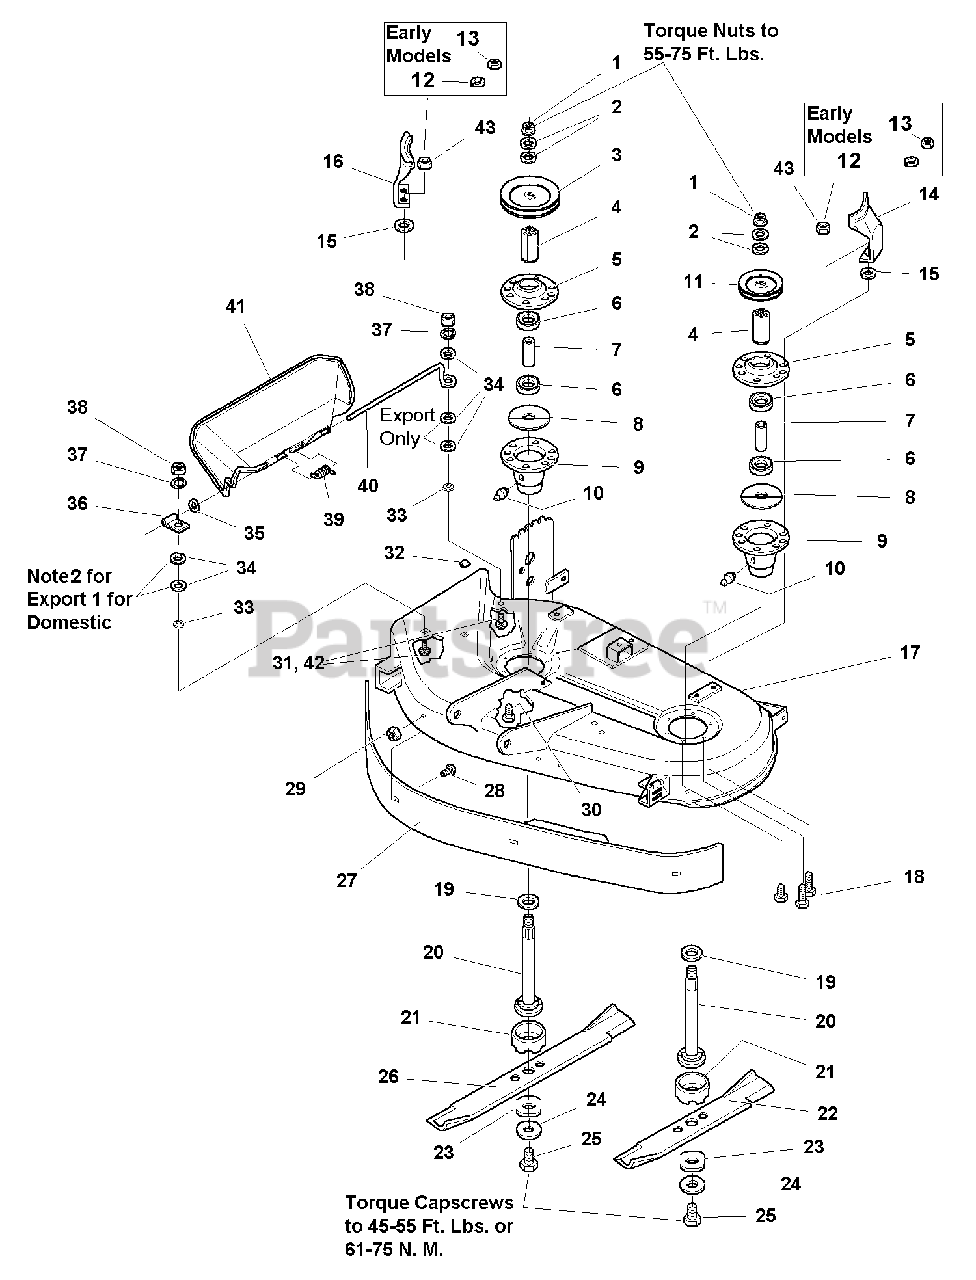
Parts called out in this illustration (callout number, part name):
1	NUT, Hex, Flange, 9/16-8
2	WASHER, Belleville
5	COVER, Arbor Housing
8	GASKET, Foam
9	HOUSING ASSEMBLY, Arbor Bottom, w/Lube Fitting
10	FITTING, Grease
12	LOCKWASHER, 5/16 (Early Models)
13	NUT, Hex, 5/16-18 (Early Models)
14	BELT STOP, LH
15	WASHER, Flat, 3/8
16	BELT STOP, RH
17	MOWER DECK HOUSING, 38" Orange
17	MOWER DECK HOUSING, 38" Red
18	SCREW, Taptite, 5/16-18 x 1
20	SHAFT, Arbor
21	SHIELD, Grass, Lower
22	BLADE, Mower, 16-1/8
23	WASHER, Hex
24	WASHER, Spring
25	CAPSCREW, Hex, Head, 7/16-14 x 1-1/4
26	BLADE, Mower, 22-1/4
27	BAFFLE, Blowout, 38" (Includes Ref. Nos. 28 & 29)
28	CARRIAGE BOLT, 5/16-18 x 5/8
29	NUT, Flange Lock, 5/16-18
30	SCREW, Taptite, 5/16-18 x 3/4
31	CARRIAGE BOLT, 1/4-20 x 7/8 (Domestic Models)
32	PLUG, Plastic
33	NUT, Push
34	WASHER, Plain
35	WASHER, Plain, 5/16
38	NUT, Hex, 1/4-20, ESNA
40	ROD, Deflector, Front
41	DEFLECTOR, Plastic
42	CARRIAGE BOLT, 1/4-20 x 1-1/4 (Export Models)
43	NUT, Hex Whzlock, 5/16-18
